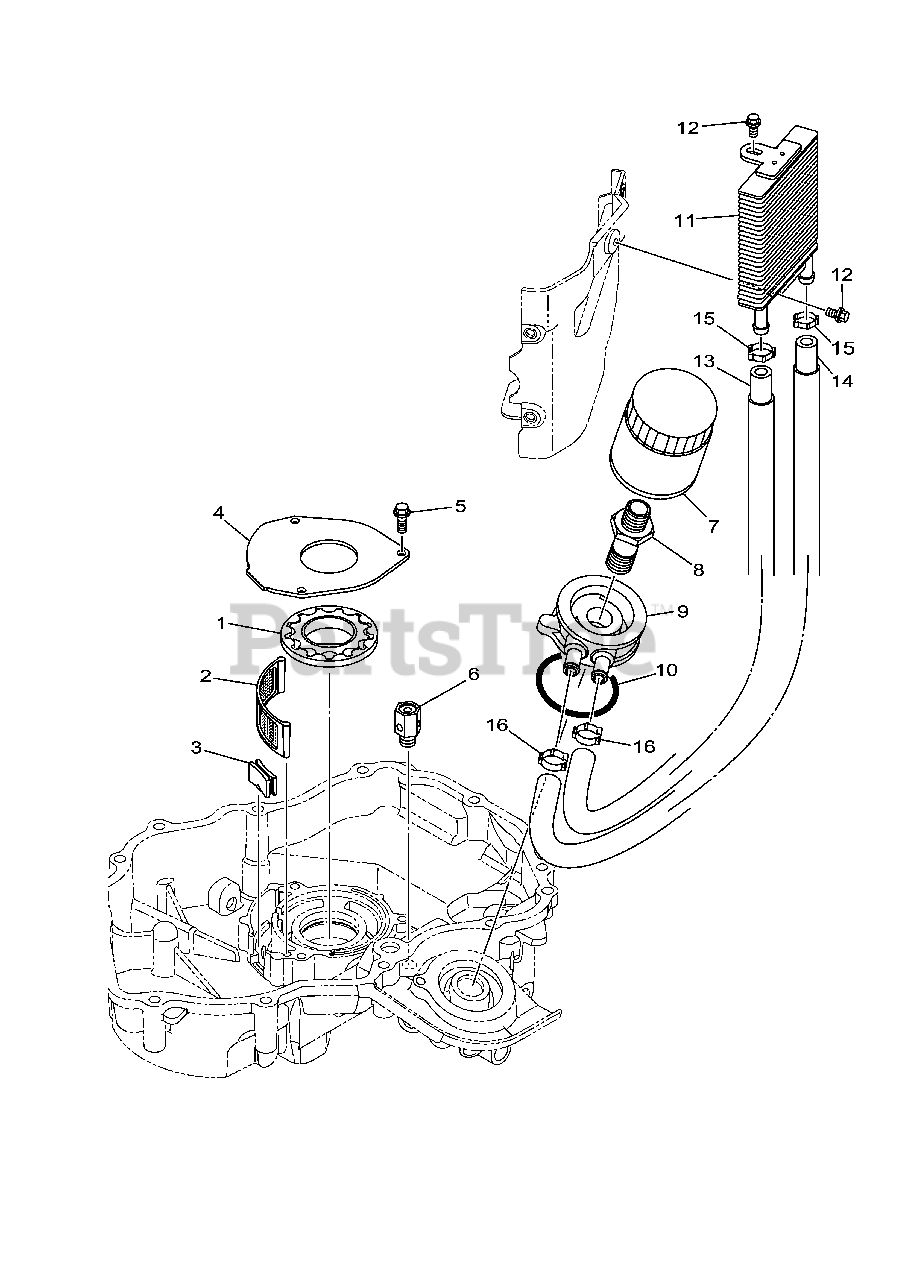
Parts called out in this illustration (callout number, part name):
1	ROTOR ASSY 1
2	STRAINER, OIL
3	COVER, STRAINER
4	COVER, PUMP
5	BOLT, FLANGE
6	RELIEF VALVE ASSY
7	FILTER, OIL - YAMAHA 824
8	BOLT, UNION
9	ADAPTER
11	OIL COOLER ASSY
12	BOLT, FLANGE
13	HOSE, OIL 1
14	HOSE, OIL 2
